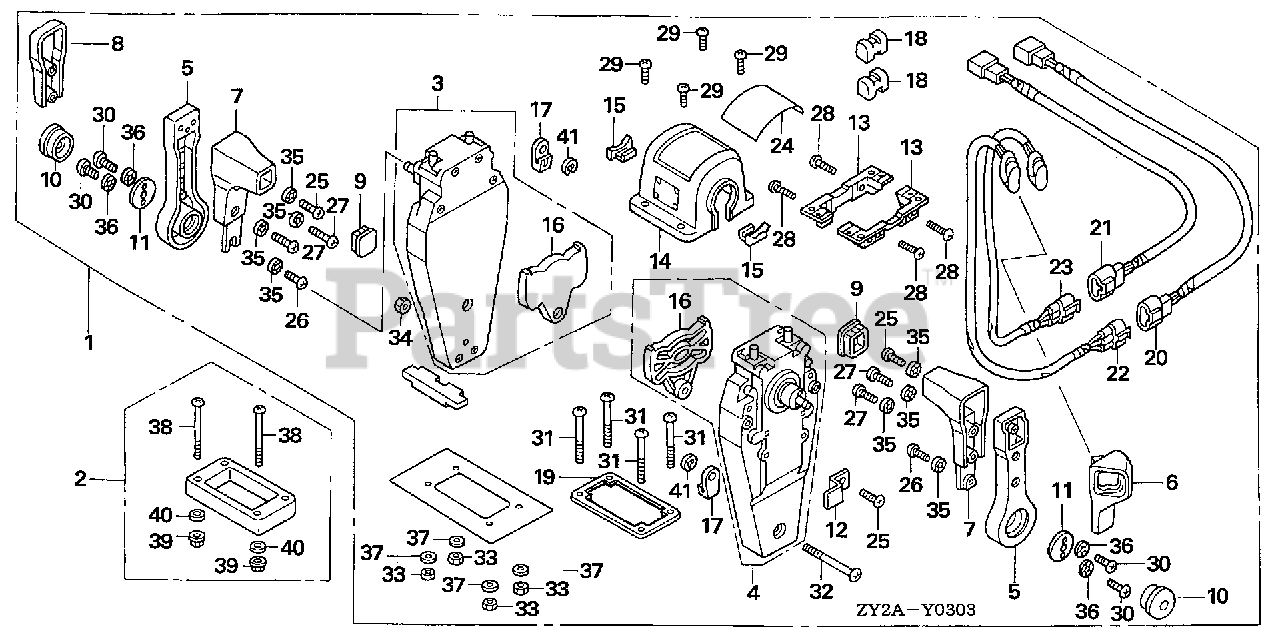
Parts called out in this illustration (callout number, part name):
1	BOX KIT, REMOTE CONTROL (TOP MOUNT DUAL)(L)
2	SPACER KIT, REMOTE CONTROL BOX (TOP MOUNT DUAL)
3	HOUSING ASSY., L. (INNER) (TOP MOUNT)
4	HOUSING ASSY., R. (INNER) (TOP MOUNT)
5	HANDLE, REMOTE CONTROL
6	COVER, R. GRIP
7	GRIP, REMOTE CONTROL HANDLE
8	COVER, DUAL GRIP
9	CAP, GRIP
10	BUTTON, THROTTLE
11	PLATE, HANDLE
12	PLATE, CABLE CLAMP
13	BRACKET, REMOTE CONTROL HOUSING
14	HOUSING, DUAL REMOTE CONTROL BOX
15	HOUSING, LEAD
16	PLATE, DWELL
17	TERMINAL, CABLE
18	SPACER, CABLE CLAMP
19	GASKET, DUAL
20	SUB-HARNESS ASSY., POWER TRIM-TILT (A)
21	SUB-HARNESS ASSY., POWER TRIM-TILT (B)
22	SWITCH ASSY., POWER TRIM-TILT (A)
23	SWITCH ASSY., POWER TRIM-TILT (B)
24	MARK, REMOTE CONTROL (DUAL)
25	SCREW, PAN (5X16)
26	SCREW, PAN (5X10)
27	SCREW, PAN (5X20)
28	SCREW, PAN (5X18)
29	SCREW, PAN (4X10)
30	SCREW, PAN (6X18)
31	SCREW, PAN (5X40)
32	SCREW, PAN (5X55)
33	NUT, HEX. (5MM)
34	NUT, HEX. (5MM)
35	WASHER, LOCK (5MM)
36	WASHER, LOCK (6MM)
37	WASHER, PLAIN (5MM)
38	SCREW, PAN (5X65)
39	NUT, HEX. (5MM)
40	WASHER, PLAIN (5MM)
41	E-RING (6MM)
